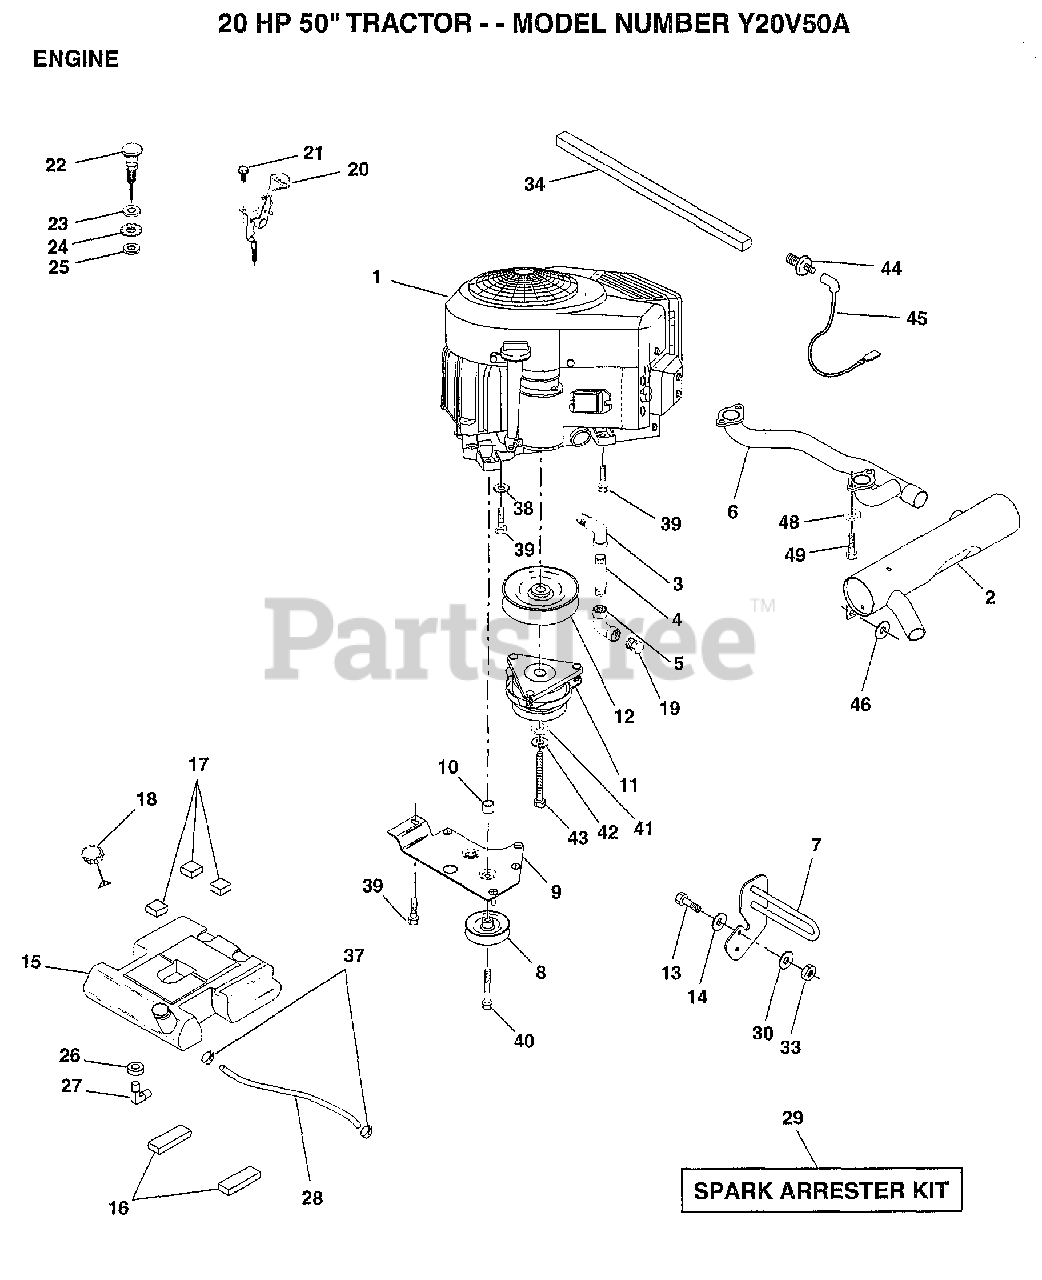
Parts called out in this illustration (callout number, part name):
3	STREET ELBOW LT
4	PIPE NIPPLE
5	ELBOW
6	PIPE.EXHAUST.B&S
10	BUSHING.
12	PULLEY.ENGINE.VGT
13	"BOLT,HEX"
14	WASHER
16	PAD IDLER TI
17	PAD-SPACER LT
18	CAP ASM FUEL
19	PLUG T
21	SCREW LT
23	WASHER
24	LOCKWASHER
26	BUSHING OUTLET T
27	STEM.TANK.FUEL
29	SPARK ARREST KIT
30	WASHER T
33	NUT
34	FOAM-STRIP LT
37	HOSE CLAMP
38	LOCKWASHER
39	SCREW LT
40	SCREW.3/8-16X3.25
41	WASHER
42	LOCKWASHER
44	SWITCH OIL KOHLER
45	WIRE.LEAD.SENTRY
46	WASHER HYT
48	LOCKWASHER
49	BOLT.HD.SOCKET.
